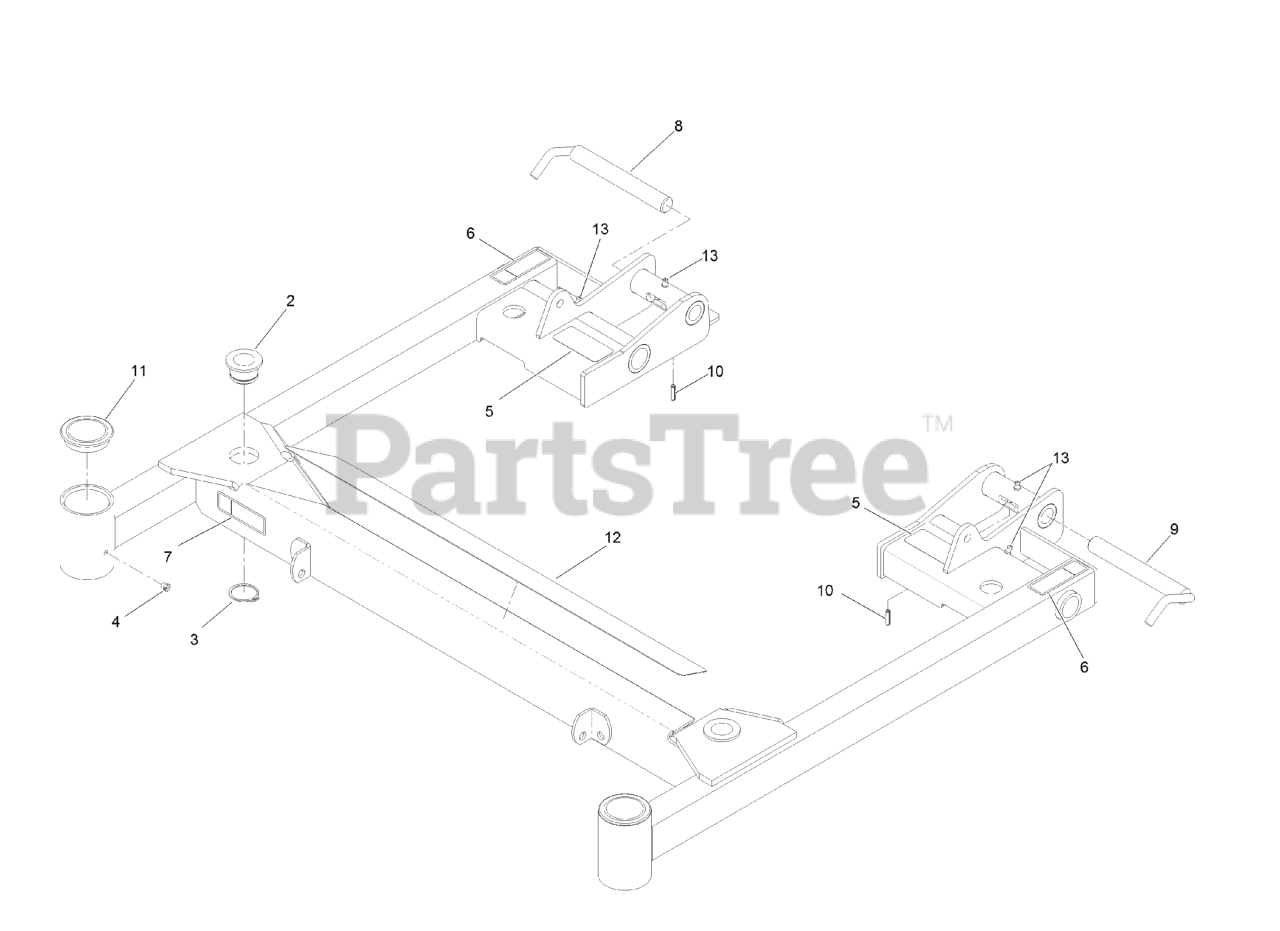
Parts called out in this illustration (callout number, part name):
2	BUSHING-SUPPORT, DECK
3	RING-RETAINING
5	DECAL-WARNING
6	DECAL-WARNING, FOLDING DE
7	DECAL-DANGER
8	LOCK-DECK, RH
9	LOCK-DECK, LH
10	PIN-SPRING
11	CAP-GREASE
12	PAD-ANTI SKID
13	FITTING-GREASE
